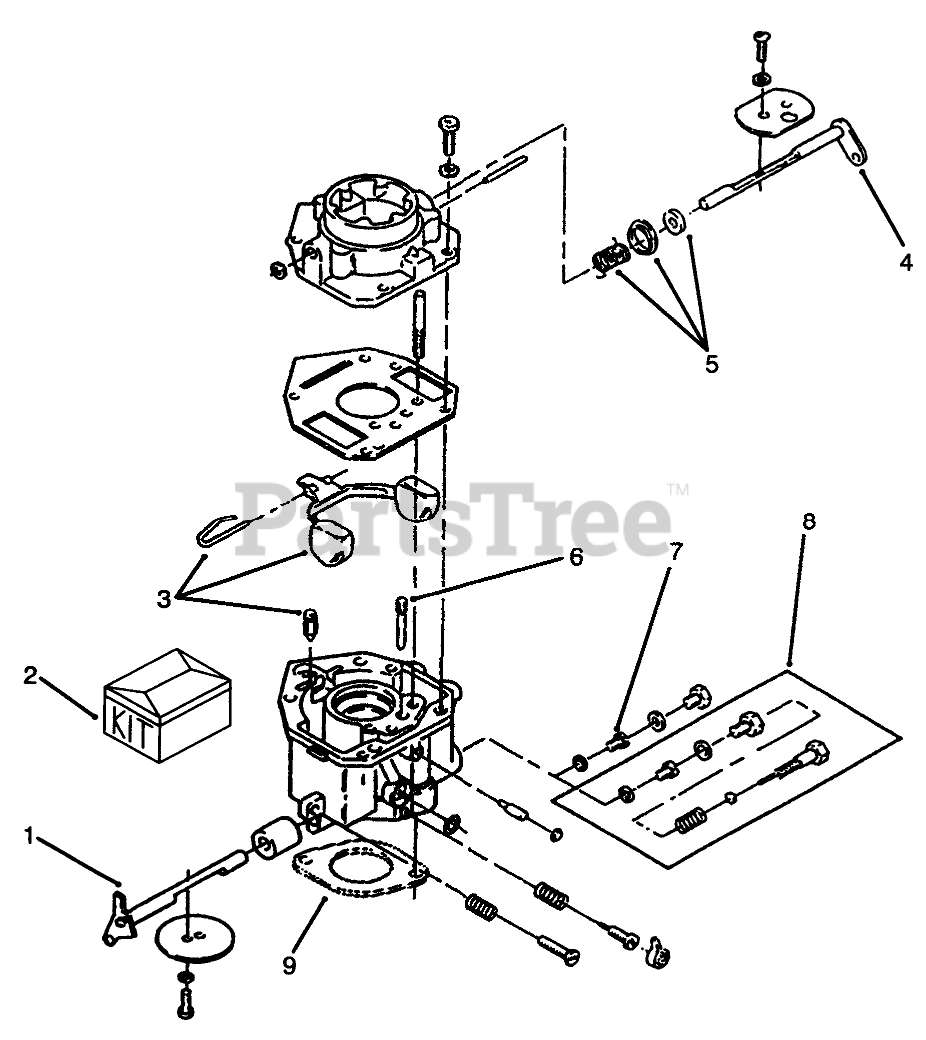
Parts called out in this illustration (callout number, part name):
1	Kit-Shaft, Throttle (Incl. Valve Setscrew, Air Filter, & Throttle Valve)
2	Kit-Repair (Incl. Screw & Plug Package, Gasket Package, Float Valve, Idle Adj. Needle & Spring, Mounting Gaskets, & Idle Limit Cap)
3	Kit-Float (Incl. Float, Pin & Valve) Before Serial No 5902947
4	Kit-Shaft, Choke (Incl. Choke Valve, Valve Setscrew, & Air Filter)
5	Kit-Lever, Choke (Incl. Choke Lever Ring, Choke Spring, & Choke Collar)
6	IDLE-JET
7	POWER JET
8	FIXED-JET
9	GASKET-CARBURETOR
